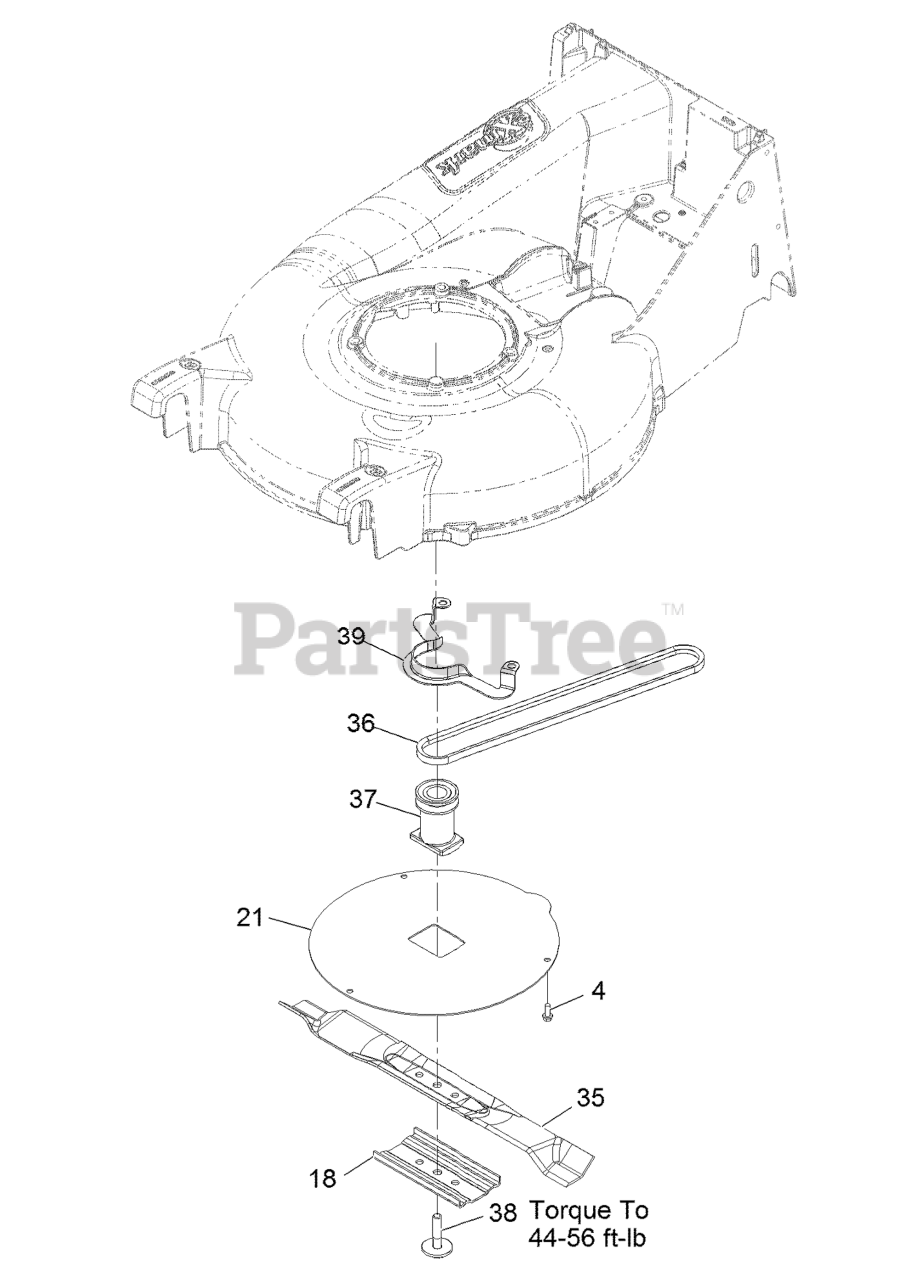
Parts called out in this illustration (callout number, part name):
4	SCREW-HWH
18	SUPPORT-BLADE
35	Blade - Medium Lift, 20.5
36	BELT,3L P21 DRIVE
37	BLADE-ADAPTER
38	BOLT-BLADE, SEM
39	GUIDE-BELT
